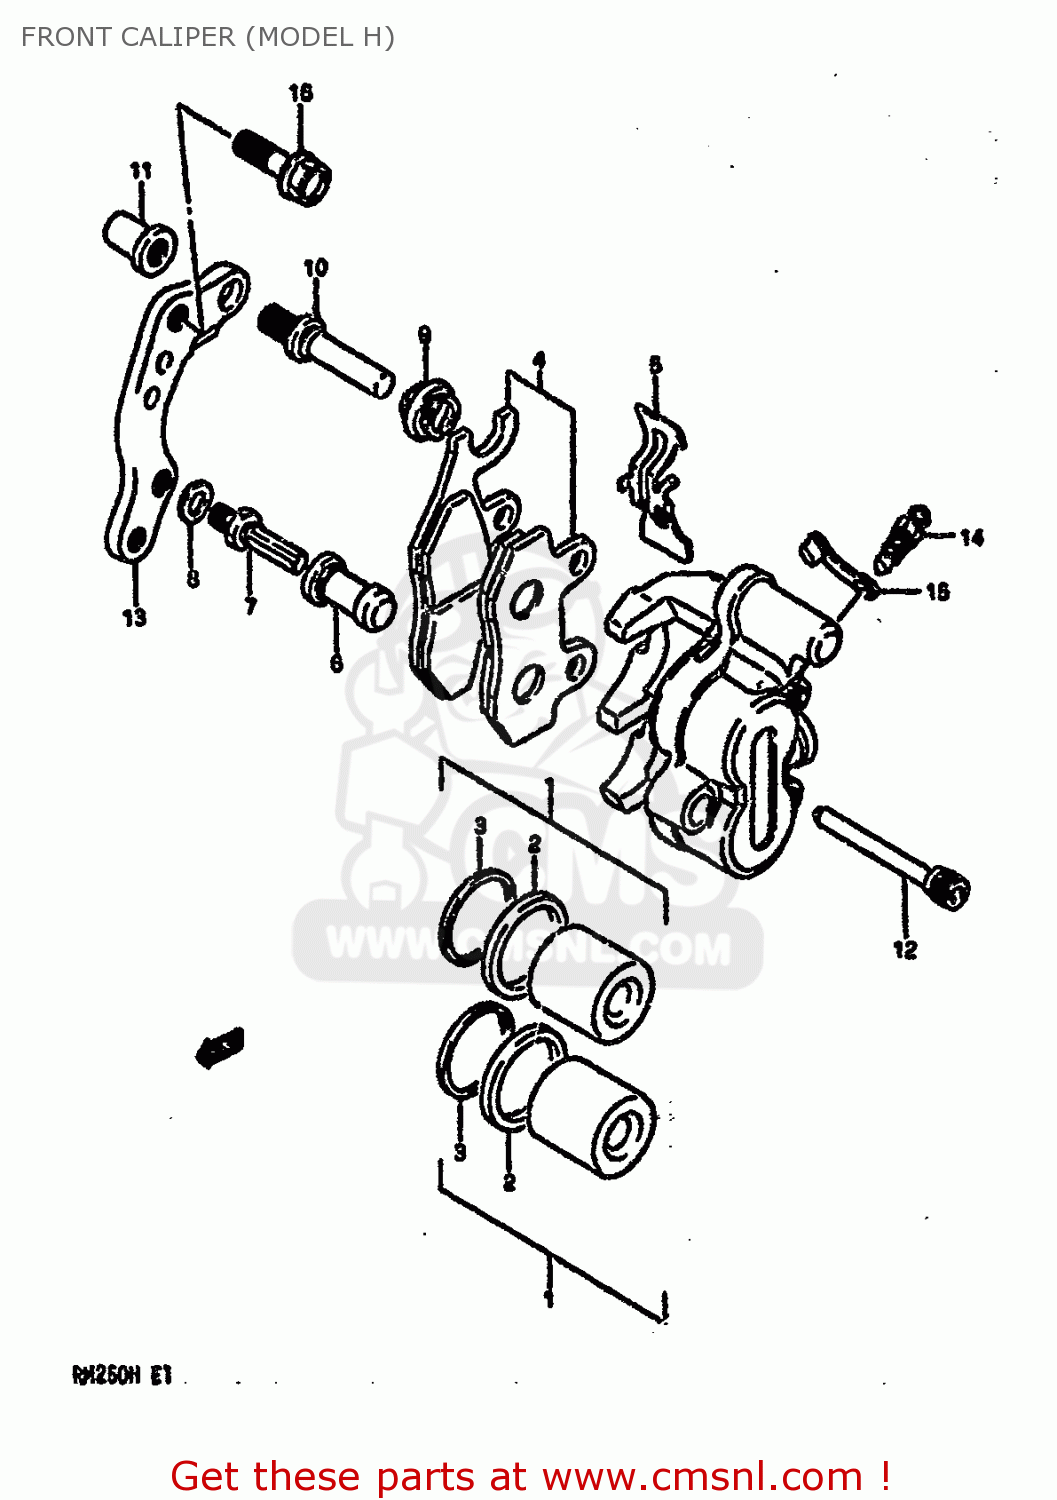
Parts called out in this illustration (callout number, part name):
1	CALIPER ASSEMBLY,FRONT,LEFT
2	SEAL,PISTON
3	SEAL,DUST
4	CALIPER ASSEMBLY,FRONT,LEFT
5	SPRING
6	BOOT
7	BOLT,PIN
8	WASHER,WAVE
9	BOOT
10	PIN,SLIDE
11	NUT
12	PIN,HOLDER
13	BRACKET
14	BLEEDER
15	CAP,BLEEDER
16	BOLT(8X24)
